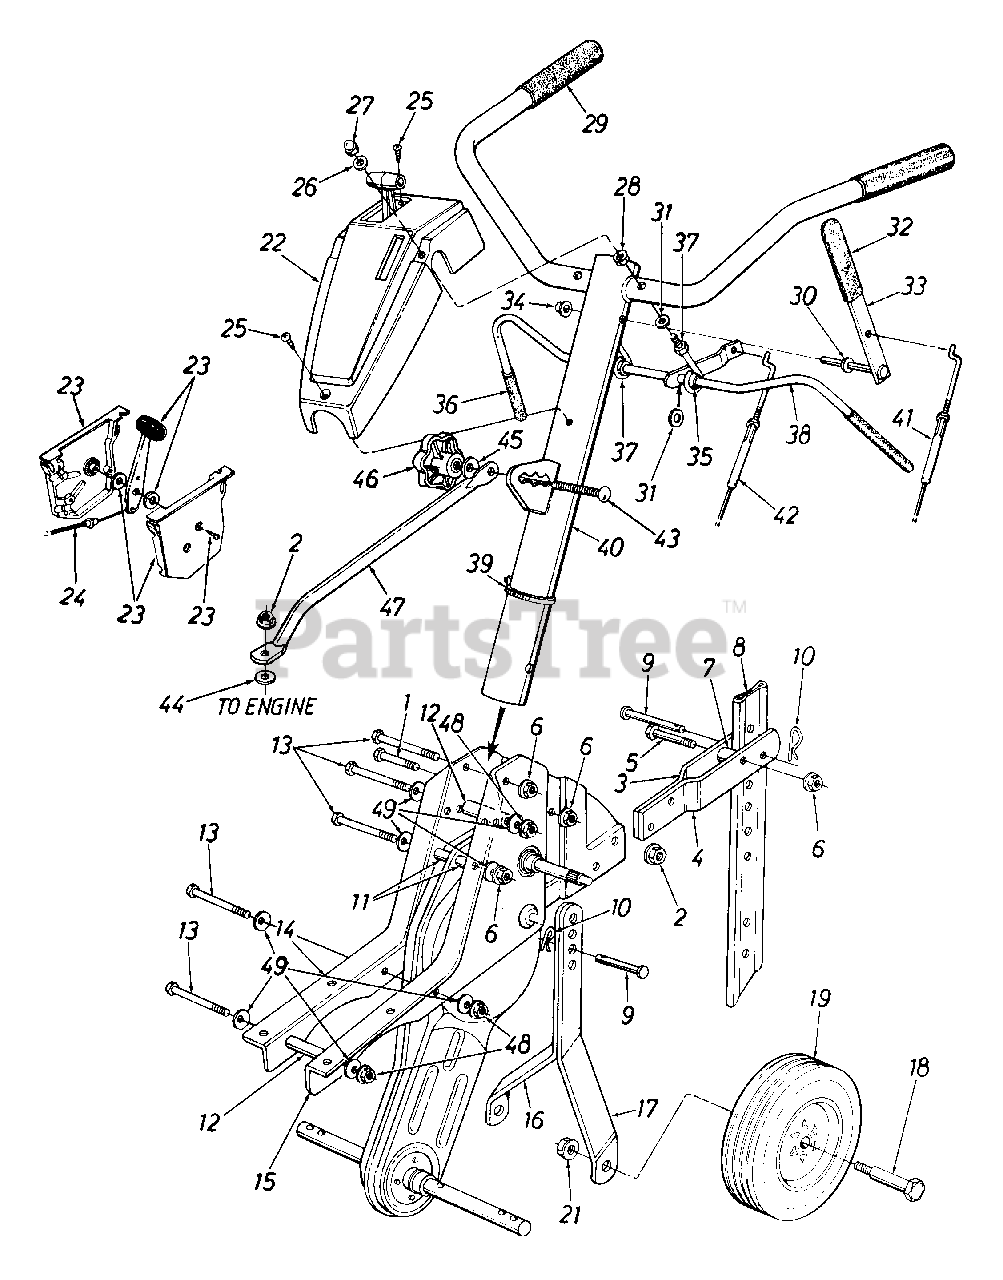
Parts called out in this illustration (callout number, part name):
1	Hex Bolt 5/16-18 x 1.25" Lg.
2	Hex Flange L-Nut 5/16-18 Thd. (Gr. 5)
5	Hex Bolt 5/16-18 x 1.5" Lg.
6	Hex Flange L-Nut 5/16-18 Thd. (Gr. 5)
7	Spacer .32" I D. x .75" O.D.
9	Clevis Pin .375" I.D. x 1.75" Lg.
10	Internal Cotter Pin
11	Spacer .326" I.D. x .47" O.D.
12	Spacer 322" I.D. x.44" I.D.
13	Hex Bolt 5/6-18 x 2.75" Lg.
17	Wheel Hanger Brkt. - L.H.
18	Shld. Bolt .498" Dia. x 1.45" Lg.
19	Wheel Ass'y. 8" x 1.75"
22	Handle Cover w/Reverse
23	Throttle Control Box Ass'y.
24	Throttle Control Wire 35" Lg.
25	Truss Mach. AB-Tap Scr. #10 x .5" Lg.
26	Fl-Wash. .266" I.D. x.625" O.D.
27	Hex L-Stop Nut 1/4-28 Thd.
28	Hex Nut 1/4-28 Thd.
29	Grip - Handle
30	Fl-Wash. .344" I.D. x.62" O.D.
31	Fl-Wash. .385" I.D. x.62" O.D.
32	Grip - Reverse Lever
33	Reverse Handle Ass'y.
34	Cap Speed Nut
35	Plastic Bushing .38" I.D.
36	Grip - Clutch
37	Clutch Handle Eye Bolt
42	Clutch Control Cable - Forward
43	Carr. Bolt 5/16-18 x 1" Lg. (Special)
44	Fl-Wash. .344" I.D. x 1.12" O.D.
45	Bell-Wash. .345" I.D. x .88" O.D.
46	Hand Knob
49	Bell-Wash. .345" I.D. x .88" O.D.
